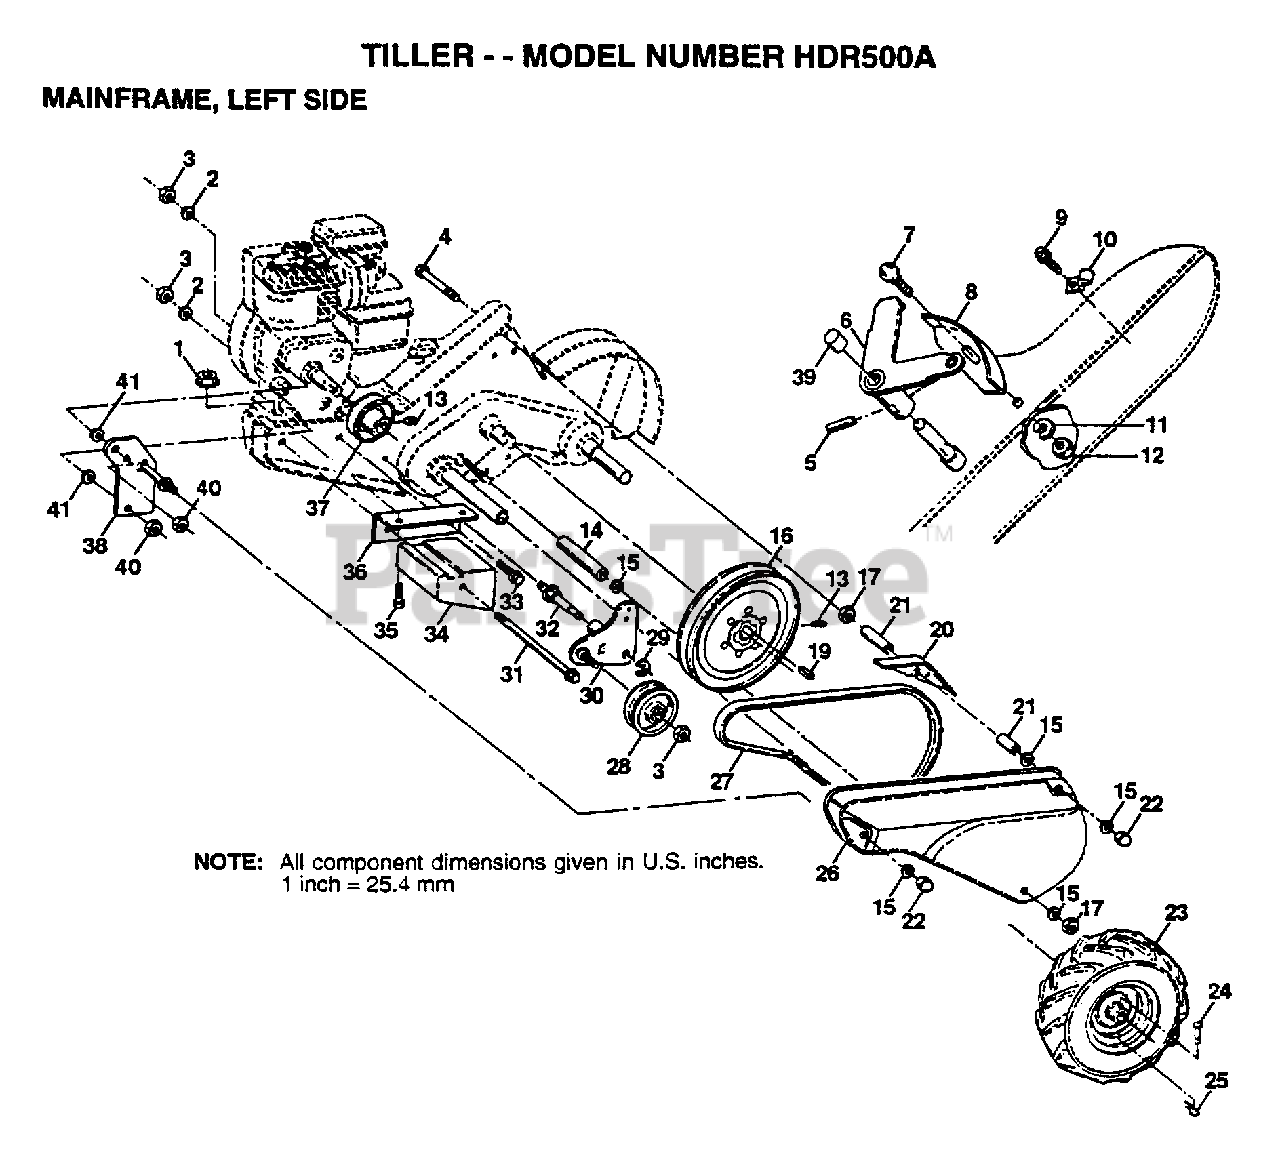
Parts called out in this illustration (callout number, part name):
2	LOCKWASHER
3	NUT.HEX.3/8-16UNC
4	BOLT TI
6	LEVER ASM CRT
7	BOLT
8	PANEL TI
10	CONDIUT CLIP T
11	LOCKWASHER
13	SET SCREW
14	SPACER
15	WASHER
16	"SHEAVE 10"" CRT"
17	NUT.HEX.5/16-18
18	SPACER CRT
19	KEY T
20	GUARD CRT
21	SPLIT SPACER
22	NUT TI
23	TIRE.CHV.13X5.0-6
24	RIVET.DRILL.1.75
25	RETAINER M
26	GUARD.BELT.PNT.
27	BELT-V
28	PULLEY-IDLER TI
29	KLIP RING
31	BOLT CRT
32	SHIFT ARM CRT
33	BOLT
34	COUNTERWEIGHT CRT
35	BOLT.HEX.5/16-1.5
36	BRACKET LH CRT
37	ENGINE SHEAVE
38	BELT GUARD BRKT
39	CAP PLUNGER BLACK
40	NUT
41	WASHER
